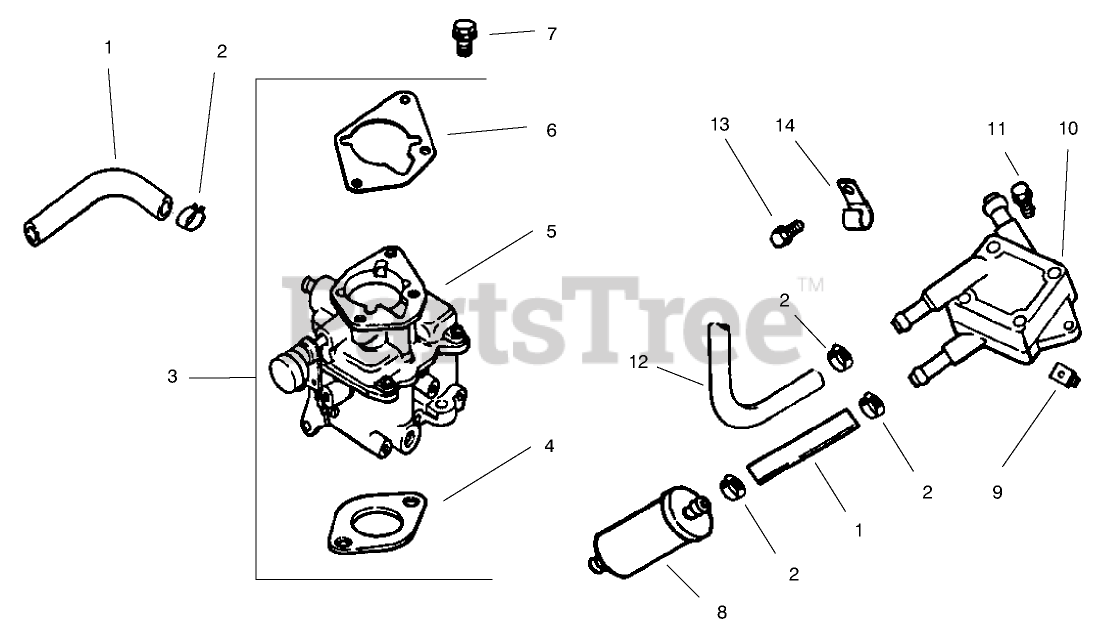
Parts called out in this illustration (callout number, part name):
1	Line fuel
2	Clamp
3	Kit, carburetor w/gasket (Includes 4-6)
4	Gasket
5	Carburetor assembly
6	Gasket
7	Screw
8	Filter-Fuel
9	Nut
10	Pump-Fuel
11	Screw
12	Line, fuel17"
13	Screw
14	Clamp
